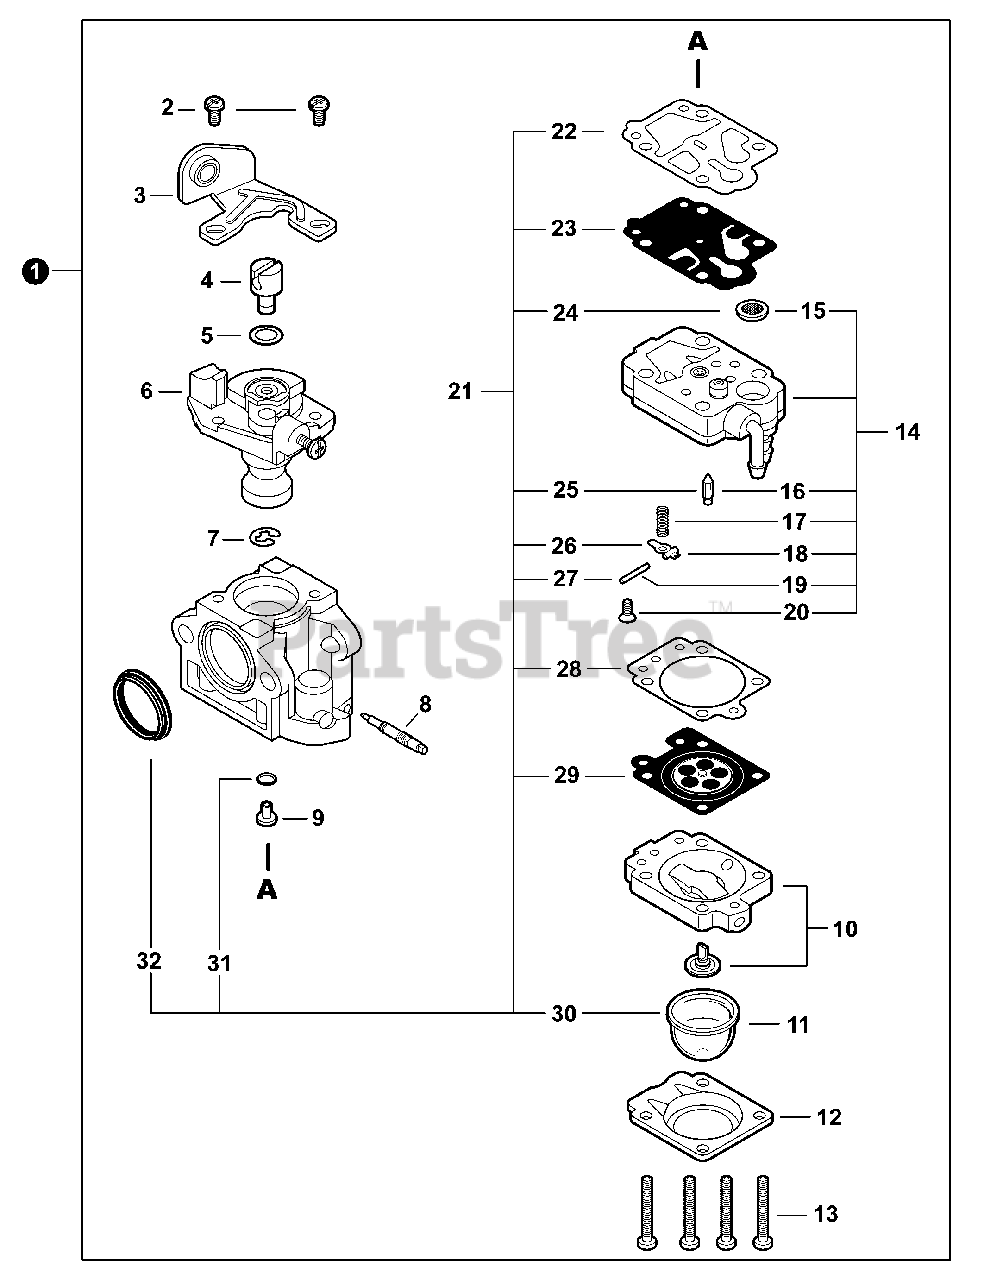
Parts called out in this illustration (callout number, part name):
1	CARBURETOR - WYK-356
3	BRACKET, THROTTLE CABLE
6	VALVE ASSY, THROTTLE
8	NEEDLE, HIGH SPEED
9	JET, MAIN #31
10	BODY ASSY, PURGE
11	BULB, PURGE
12	RETAINER, PURGE BULB
14	BODY ASSY, PUMP
15	SCREEN, INLET
16	VALVE, INLET NEEDLE
17	SPRING, METERING LEVER
18	LEVER, METERING
19	PIN, METERING LEVER
20	SCREW
21	REPAIR KIT, CARBURETOR
22	GASKET, PUMP
23	DIAPHRAGM, PUMP
24	SCREEN, INLET
25	VALVE, INLET NEEDLE
26	LEVER, METERING
27	PIN, METERING LEVER
28	GASKET, METERING DIAPHRAGM
29	DIAPHRAGM, METERING
30	BULB, PURGE
31	O-RING
32	RING, PACKING
